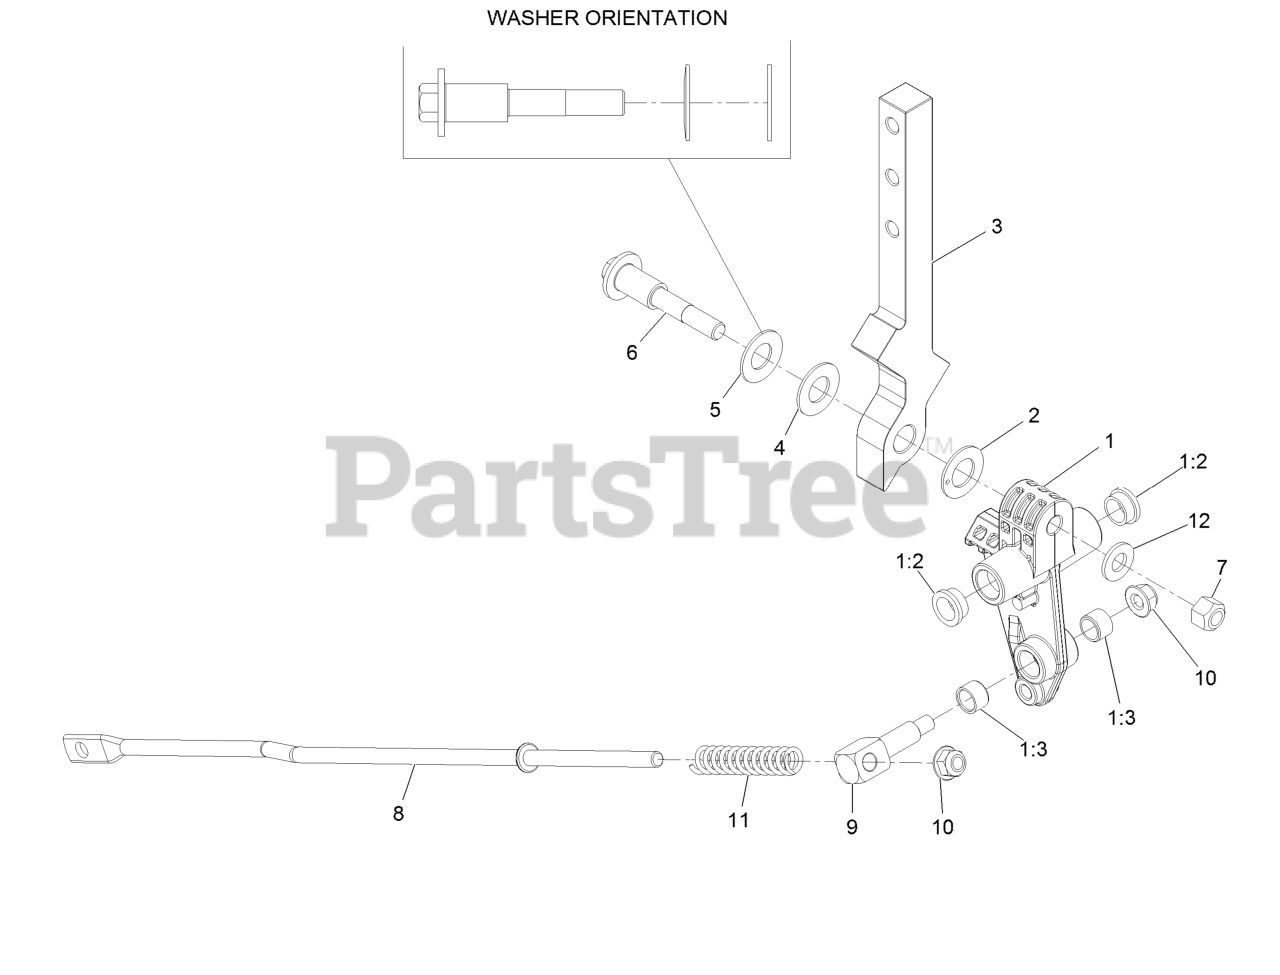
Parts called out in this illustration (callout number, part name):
1	Control Arm ASM
1:2	Bushing
1:3	Bushing-Sleeve
2	Washer-Friction
3	Arm-Control
5	Washer-Belleville
6	Bolt-Pivot
7	Nut-Hex 3/8-16 Lock
8	Link-Control
10	Nut-Nyloc 5/16-18 Flg
11	Spring-Return, Neutral
12	Washer-3/8 SAE
